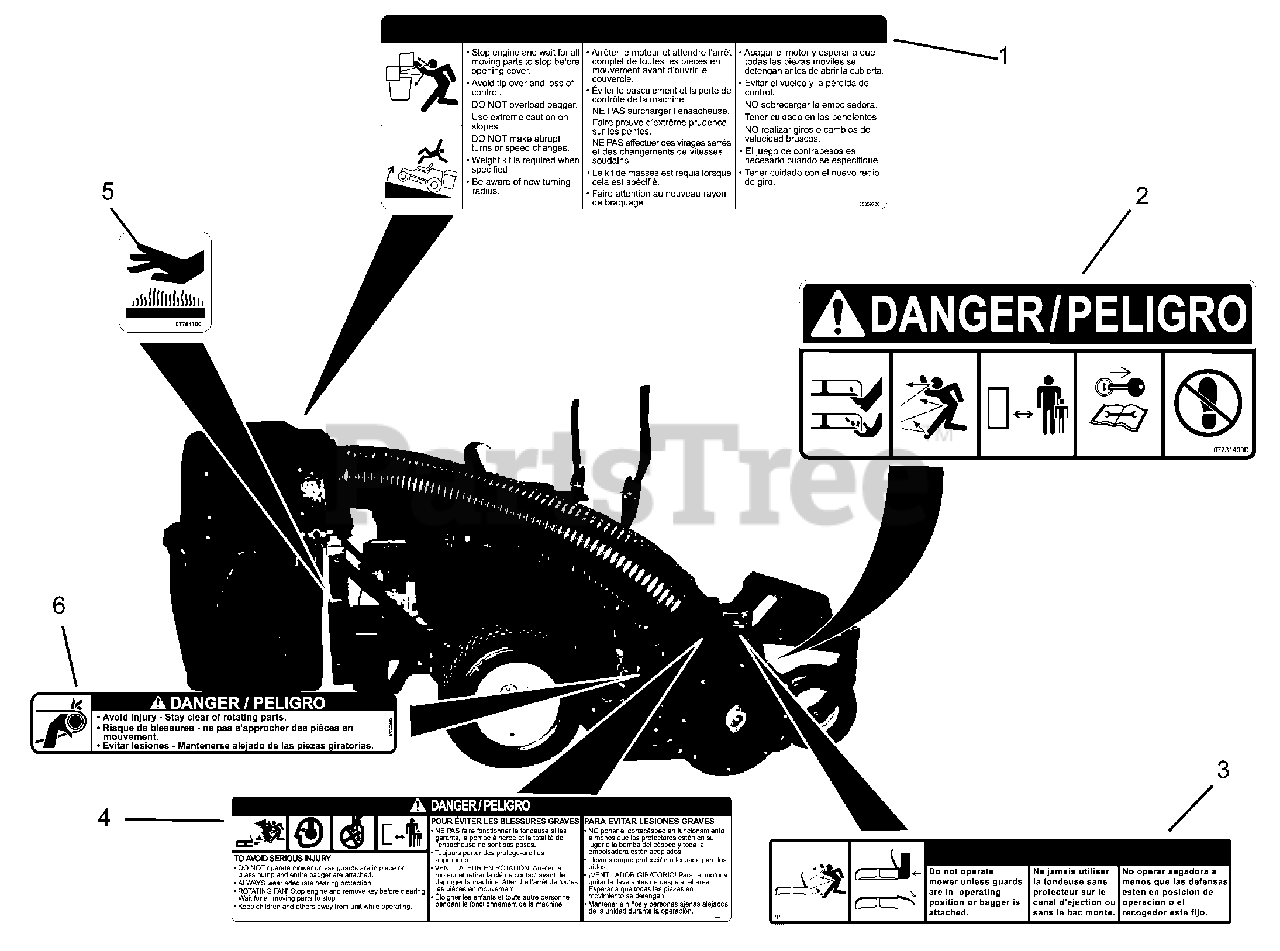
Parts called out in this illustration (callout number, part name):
1	Bagger Cover Decal
2	Mower Pan Danger Decal
3	Warning Decal
4	Grass Pump Caution Decal
5	Decal, Hot Surface
6	Decal, Belt Pinch Point
